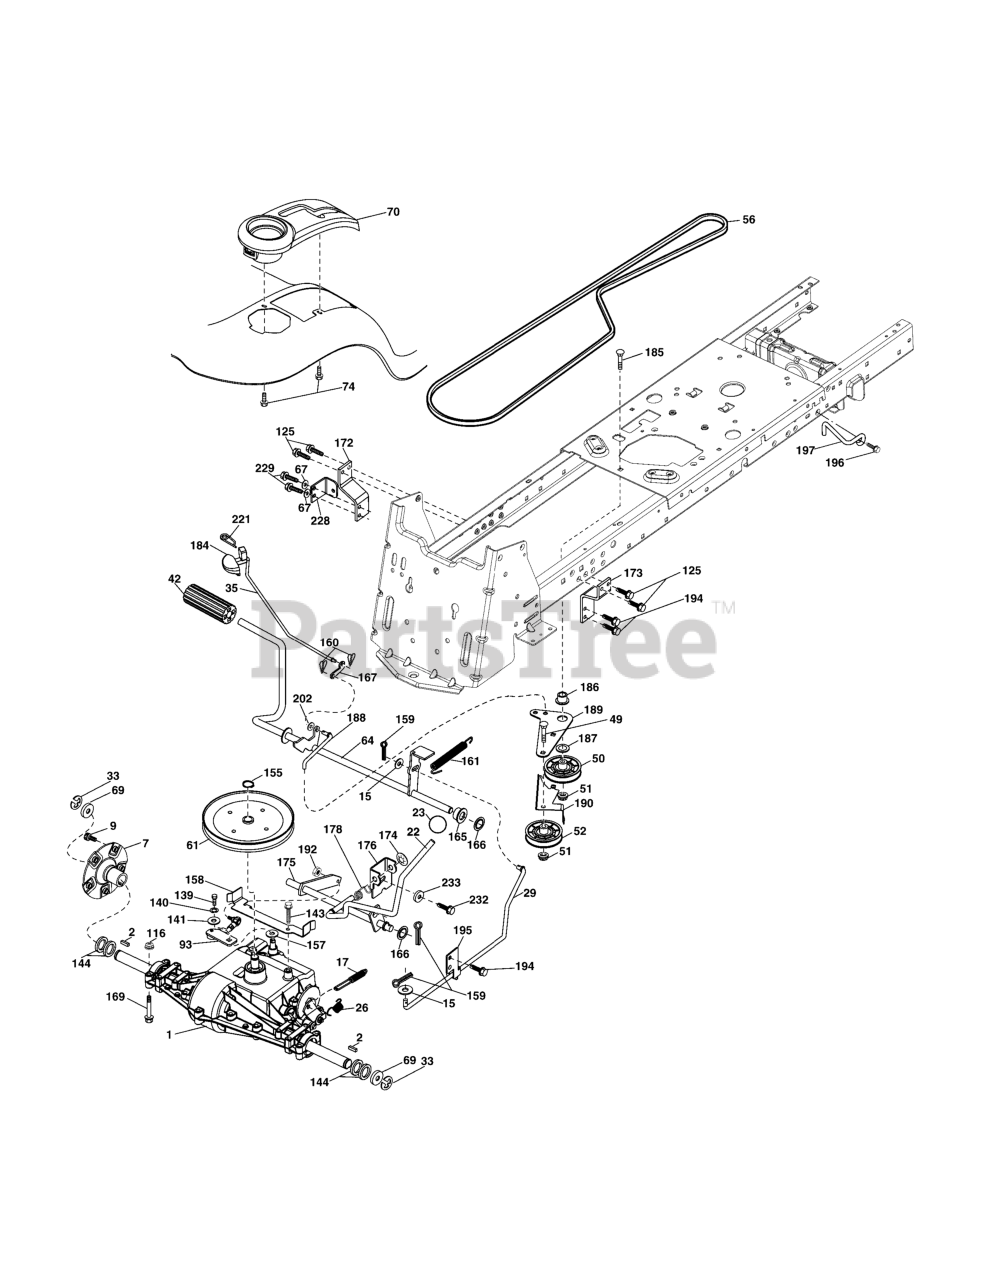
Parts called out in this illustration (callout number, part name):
2	Key 1/4 x 2.5
7	Hub Asm. Wheel Rear
9	Bolt Hub Wheel Rear
15	Washer 13/32 x 13/16 x 16 Ga.
17	Spring, Brake
22	Shift Shaft Asm.
26	Spring Brake Return
29	Rod, Brake
33	Ring E #5133-100
35	Rod, Brake, Park
42	Cover, Foot Pedal
49	Bolt
50	Pulley Idler Flat
51	Lock Nut 3/8-16
52	Idler V-Groove 910" Offset
56	V-Belt, Drive
61	Pulley Transaxle
64	Shaft Asm. Pedal Brake Control
67	Washer 13/32 x 13/16 x 12 Ga.
69	Washer
70	Console
74	Screw 1/4 x 1/2
93	Link Shift
116	Nut Lock Hex Flange 5/16-18
125	Screw 5/16-18 x 3/4
139	Bolt 1/4-28
140	Washer Lock Hvy Helical
141	Washer 9/32 x 3/4 x 10
143	Screw 5/16-18 x 1/2
144	Washer Spacer Axle
155	Ring Retainer
157	Washer Plate
158	Belt Keeper
159	Pin Cotter 1/8 x 3/4
160	Retainer Clip
161	Spring, Return, Clutch
165	Busing Shaft Brake Hand Control
166	Nut Push .625
167	Latch Brake Parking
169	Bolt 5/16-18 x Gr. 5
172	Strap Torque LH
173	Torque Strap RH
174	Nut Push
175	Shaft Asm. Shift Gear Drive
176	Arm Clevis Rod Shift
178	Spring Shift
184	Handle Parking Brake
185	Bolt
186	Spacer Retainer
187	Washer
188	Link Clutch Ground Drive
189	Bellcrank Ground Drive
190	Keeper Bellcrank Ground Drive
192	Nut Lock Center 1/4-28
194	Screw 5/16-18 x 3/4
195	Bracket Brake Rod
196	Screw 3/8-16 x 1
197	Bracket Anti-Rotation Clutch
202	Washer
221	Retainer Spring Clip Handle
228	Bracket Anti-Sway
229	Screw 5/16-18 x 1
232	Bolt 7/16-14 x 1 Gr. 5
233	Washer Serrated
